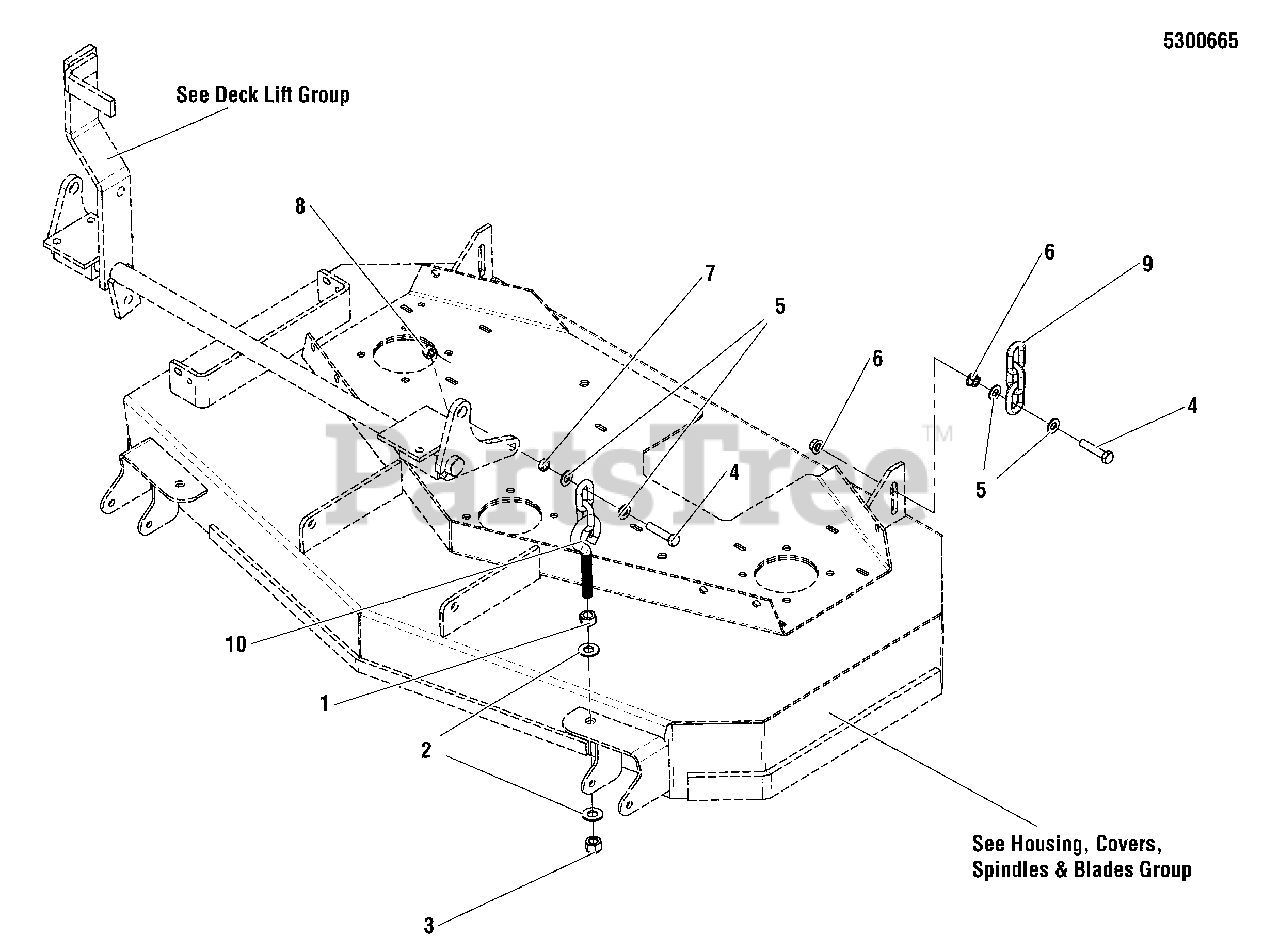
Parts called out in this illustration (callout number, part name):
1	NUT, 1/2-13 HEX
2	WASHER, 1/2 SAE
3	NUT, 1/2-13 HEX NYLON LOCK
4	BOLT, 3/8-16 X 1-3/4 GD5
5	WASHER, 3/8 SAE
6	NUT, 3/8-16 HEX SERRATED FLANGE
7	NUT, 3/8-16 HEX JAM
8	NUT, 3/8-16 HEX NYLON LOCK
9	CHAIN, 5/16 GD30, 3 LINKS
10	HANGER, FRONT DECK - 2 LINK, 5.5" EB
